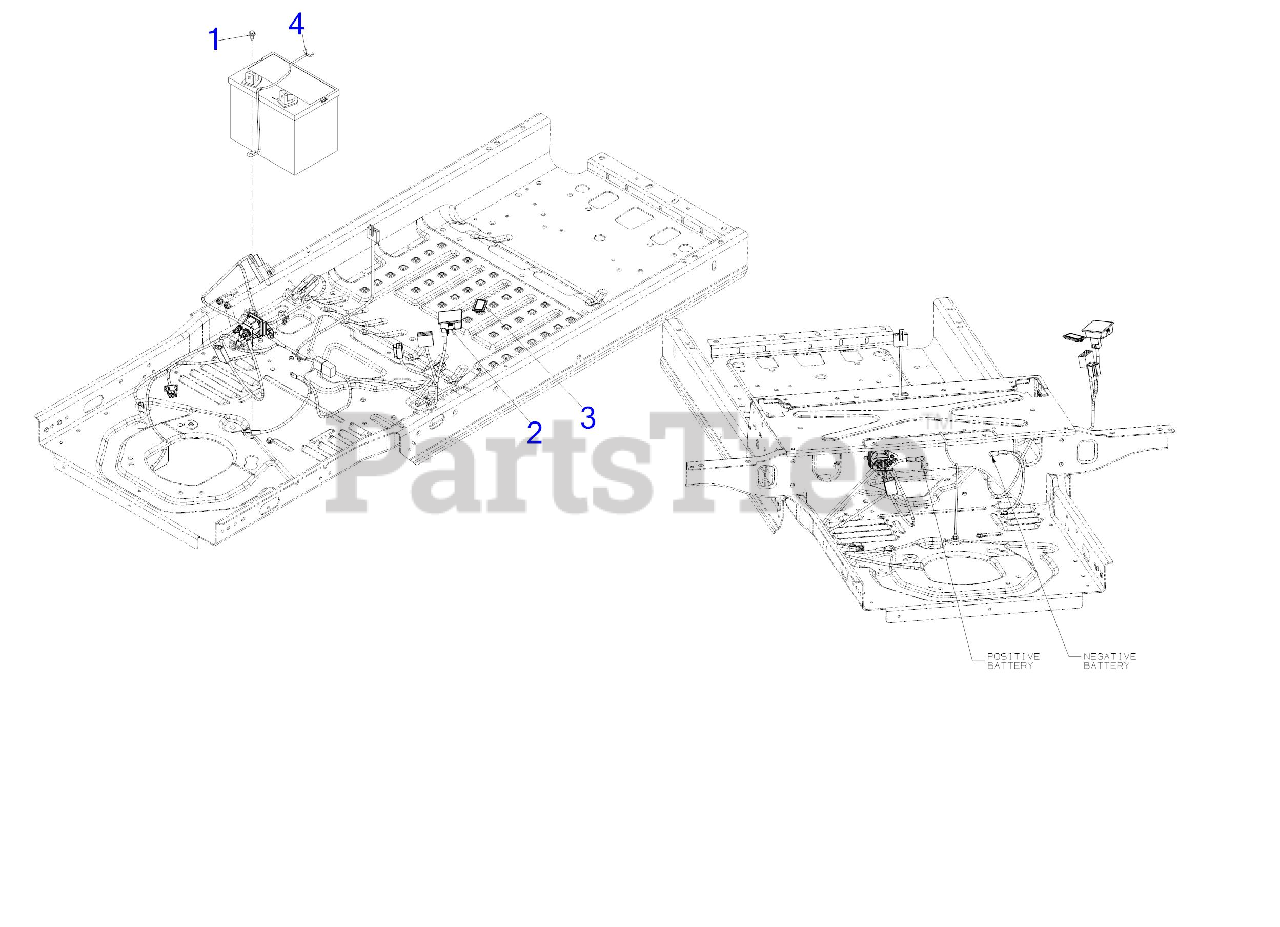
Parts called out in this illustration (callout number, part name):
1	SCREW 1/4-20X.625
2	HOUR/SVC METER
2	Cub Cadet HOUR METER KIT
2	Troy-Bilt HOUR METER KIT
3	DASH PLUG
4	BATTERY RETAINER
